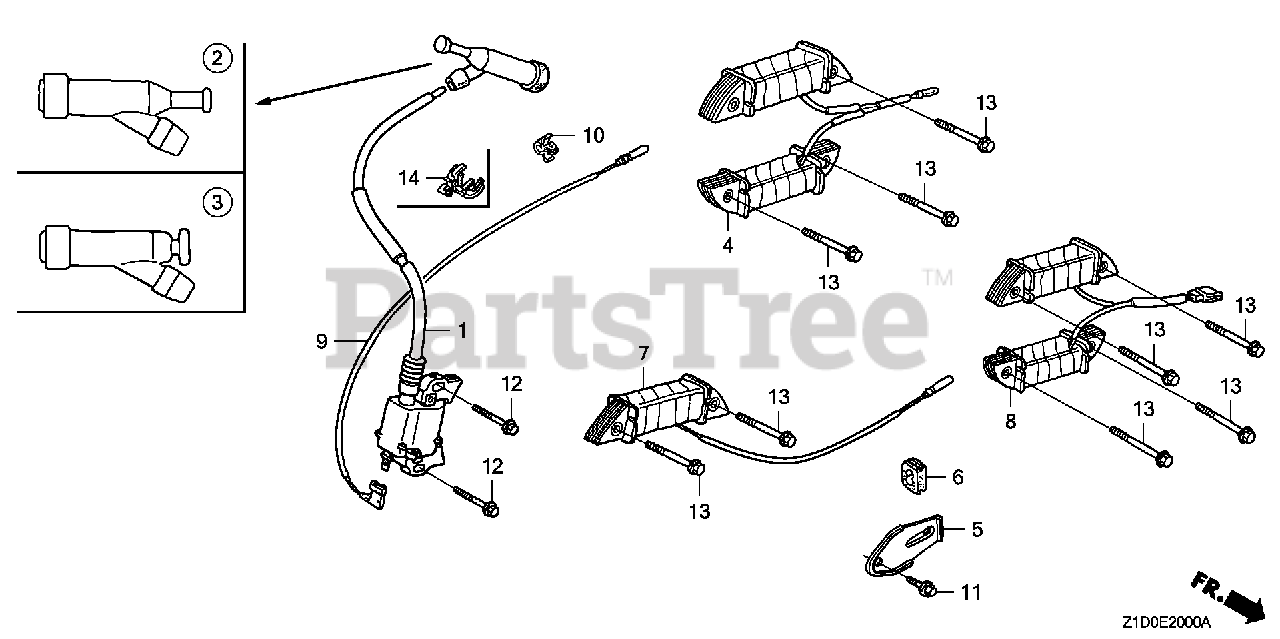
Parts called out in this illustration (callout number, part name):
1	COIL ASSY., IGNITION
3	CAP ASSY., NOISE SUPPRESSOR (NGK Y-EZD)
6	GROMMET, WIRE
9	WIRE, STOP SWITCH (370MM)
12	BOLT, FLANGE (6X28) (CT200)
14	CLIP, HARNESS
